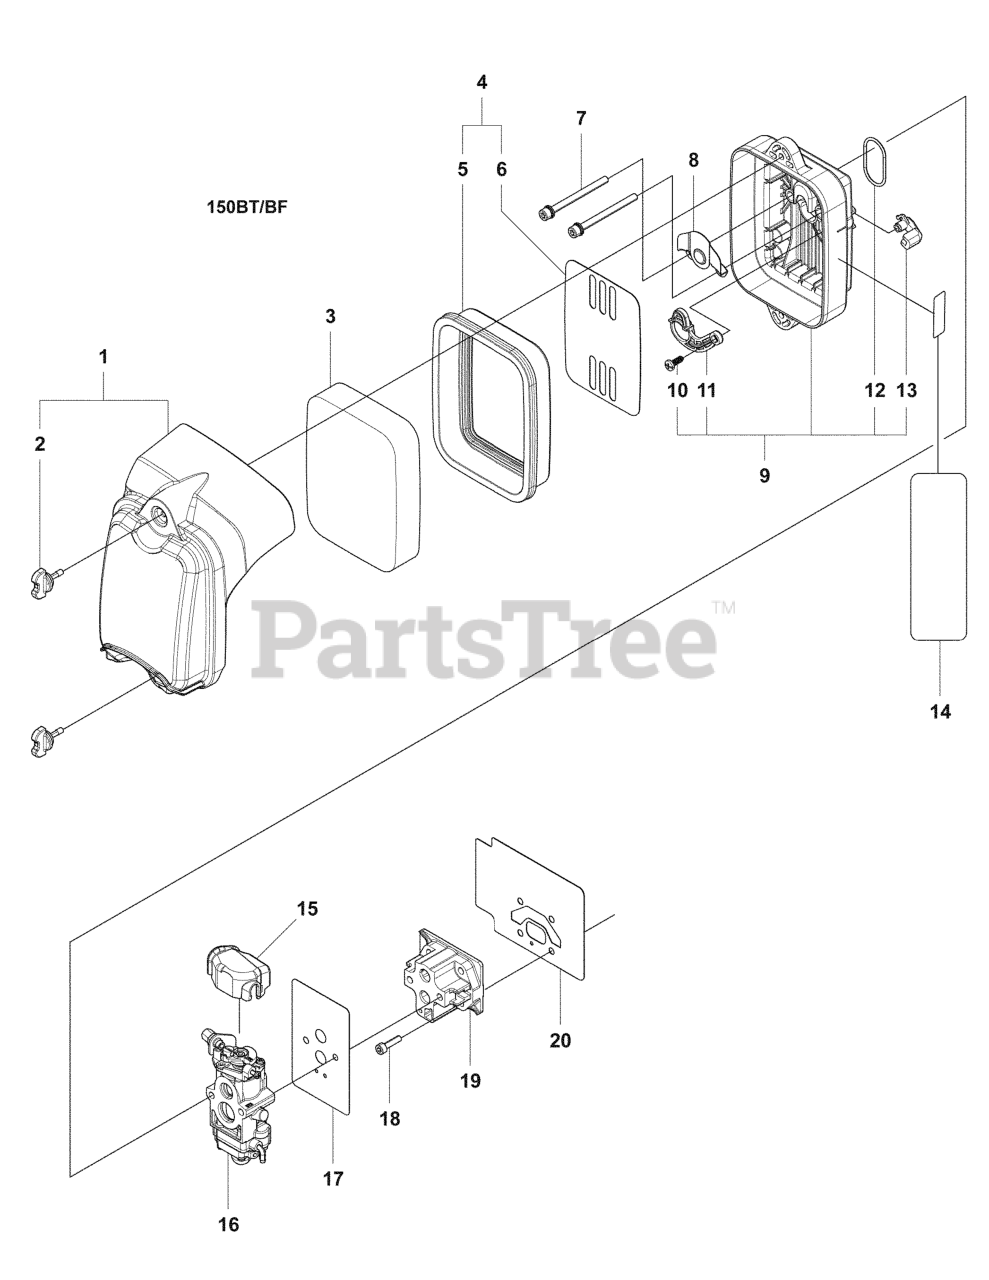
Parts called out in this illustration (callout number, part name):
3	AIR FILTER
9	CARBURETOR BODY
14	RP_LABEL, HOTMARK
15	COVER
16	CARBURETOR
18	BOLT
19	INSULATION
20	RP INSULATOR GASKET
